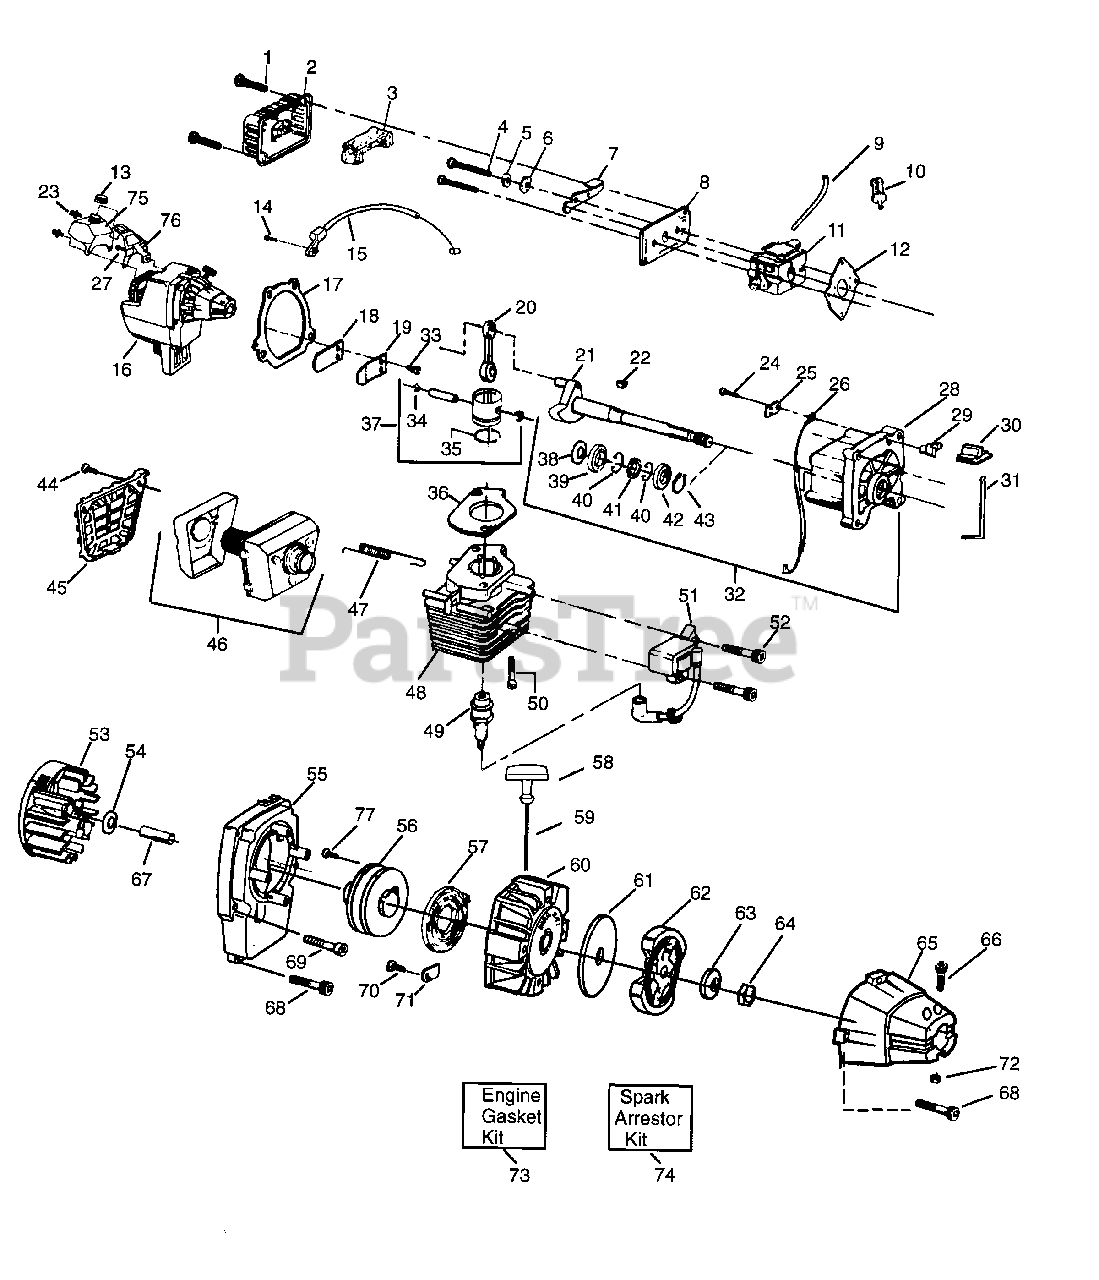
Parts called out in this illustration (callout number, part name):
2	Air Filter Cover
3	Air Filter
6	Wave Washer
7	Choke Shutter
8	Air Filter Plate
9	Fuel Line
10	Fuel Pick-up Ass'y.
11	Carburetor
12	Carburetor Gasket
13	Fuel Cap Ass'y.
15	Throttle Cable Ass'y
17	Crankcase/Shroud Gasket
19	Reed Stop
20	Connecting Rod Ass'y. (Inc. Bearings)
21	Crankshaft Ass'y. -See Service Reference 1
22	Flywheel Key
25	Switch Insulator
26	Lead Wire
27	Screw
28	Crankcase Ass'y. (Inc. 39-42)
29	Switch Ramp
30	Switch Button
31	Switch Spring
32	Crankcase & Crankshaft Ass'y (21, 28 & 39-43)
34	Piston Pin Retainer
35	Piston Ring
36	Cylinder Gasket
37	Piston Kit (Inc. 34,35 & pin)
39	Inner Bearing
40	Retaining Ring
41	Crankshaft Seal
42	Outer Bearing
43	Crankshaft Retaining Ring
45	Muffler Guard
46	Muffler Kit
47	Muffler Attachment Spring
48	Cylinder
49	Spark Plug
51	Ignition Module Kit
52	Screw
53	Flywheel Ass'y.
54	Washer
55	Fan Housing
56	Starter Pulley
57	Starter Spring
58	Starter Handle
59	Rope Kit
60	Pulley Housing Ass'y.
61	Clutch Washer
62	Clutch Ass'y. Kit
65	Clutch Housing
71	Retainer
73	Engine Gasket Kit
74	Spark Arrestor Kit
75	Fuel Tank Ass'y.
76	Fuel Tank Mtg. Bracket
77	Screw (Inc. in Starter Pulley Kit)
